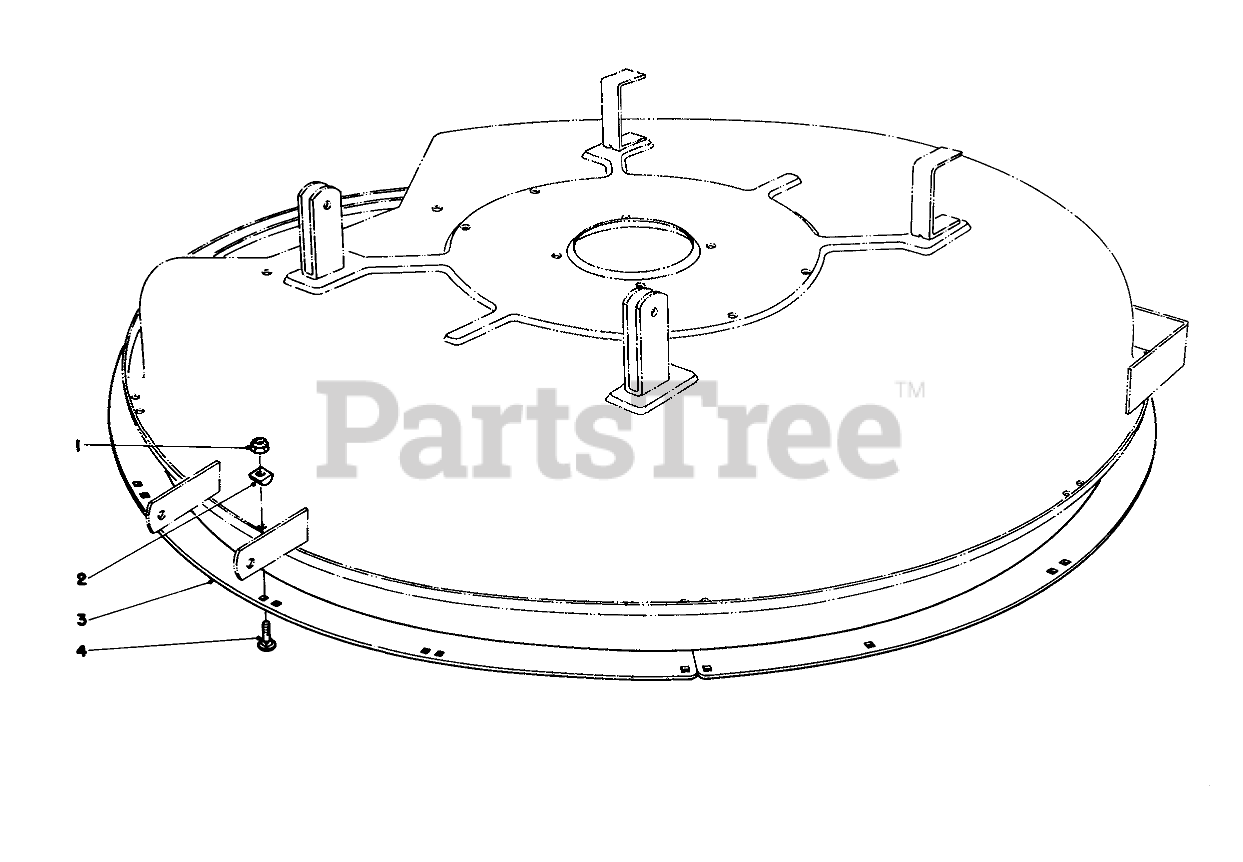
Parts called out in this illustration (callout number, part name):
1	NUT-LOCK, NI
2	Spacer-Deck Ring
3	DECK RING B
4	BOLT-CARR
